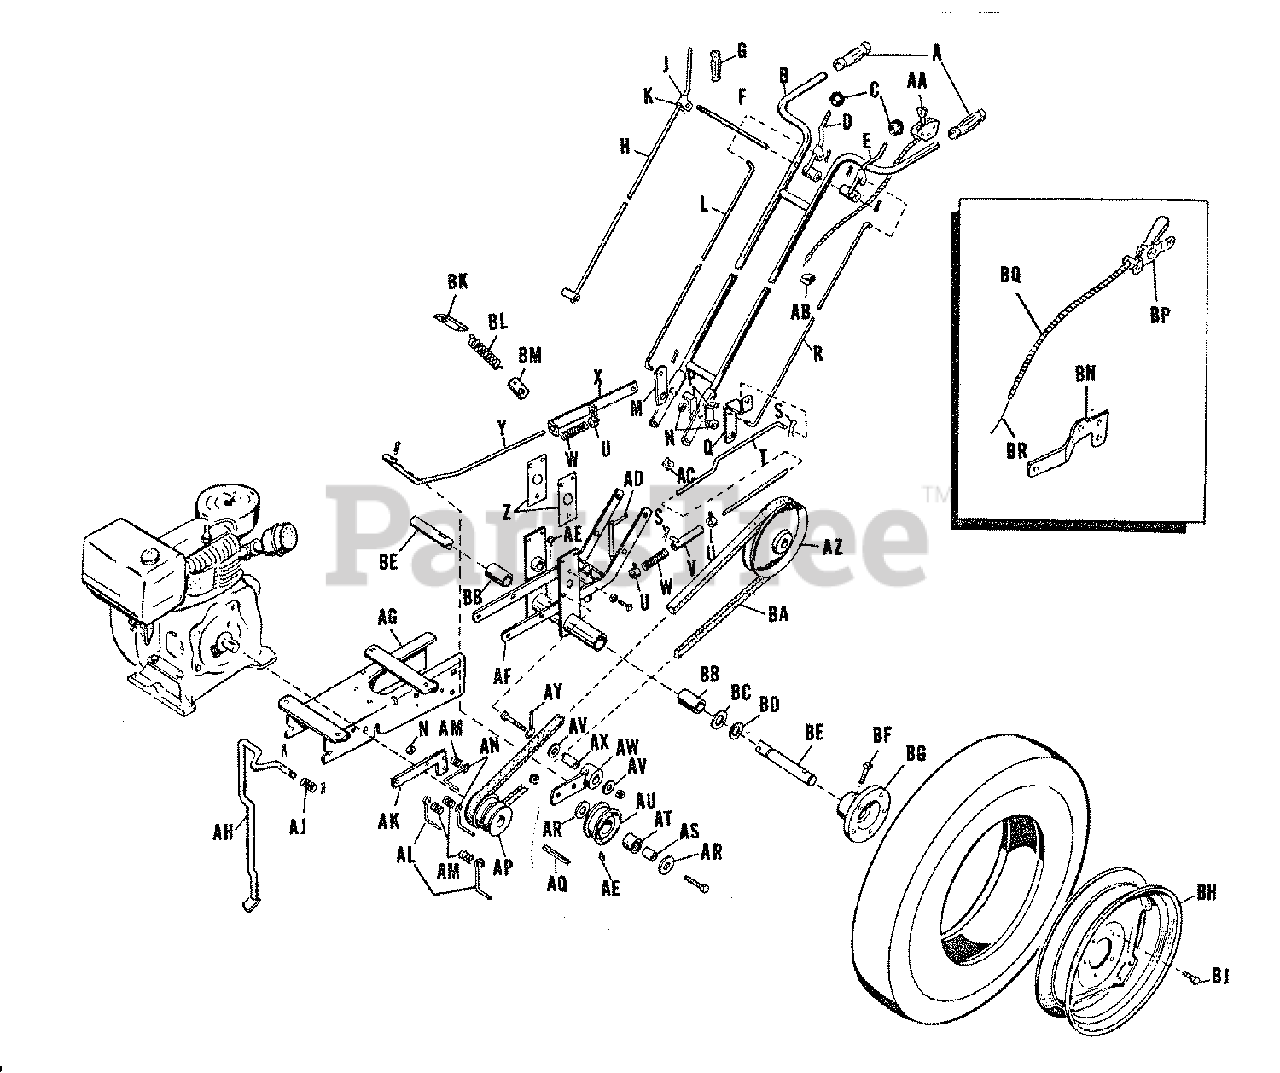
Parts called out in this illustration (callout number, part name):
A	GRIP, Handle
B	HANDLE ASSEMBLY
C	BALL, Clutch Lever
D	LEVER ASSEMBLY, Clutch, R.H.
E	LEVER ASSEMBLY, Clutch, L.H.
F	SHAFT, Lever
H	ROD ASSEMBLY, Shift
K	LINER, (Nylon)
L	ROD, Upper Idler
P	STOP, Lever
Q	LEVER, Lower Clutch
R	ROD, Clutch
S	CLIP, Spring
T	ROD, Lower Clutch
U	COLLAR, Set
V	SOCKET ASSEMBLY, Rod
W	SPRING, Idler Rod
X	GUIDE ASSEMBLY, Idler Clutch Rod
Y	ROD, Clutch, Lower Idler
Z	GASKET, Transmission Case Support
AA	THROTTLE CONTROL, With Cable & Wire (Model "H" only)
AB	CLIP, Cable
AC	CLAMP, Cable
AD	PIN ASSEMBLY, Hitch
AE	FITTING, Grease, Alemite #1641
AF	FRAME ASSEMBLY
AG	BASE ASSEMBLY
AH	STAND ASSEMBLY
AJ	SPRING, Stand
AK	HOLDER, Belt Stop
AL	STOP, Belt
AN	STOP, Belt
AP	PULLEY, Engine
AQ	KEY, Engine Pulley
AR	WASHER, Thrust
AS	RACE, Inner Bearing
AT	BEARING, Idler Pulley
AU	PULLEY, Idler
AV	WASHER, Plain 3/8"
AW	LEVER, Idler Assembly
AX	SPACER, Idler Lever
AY	PIN, Lock
AZ	PULLEY, Transmission
BA	BELT, Drive, 45" Super Combine
BB	BEARING, Axle
BD	RING, Retaining
BF	SCREW, Square Head, Set, 3/8-16 x 1-/4
BG	HUB, Wheel, L.H.
BH	WHEEL, Drive (Specify Color)
BK	HOLDER, Spring, Upper
BM	HOLDER, Spring, Lower
BN	HOLDER, Belt Stop
BP	CONTROL, Throttle Lever (Model "VC" Only)
BQ	CABLE, Throttle (Model "VC" Only)
BR	WIRE, Throttle (Model "VC" Only)
